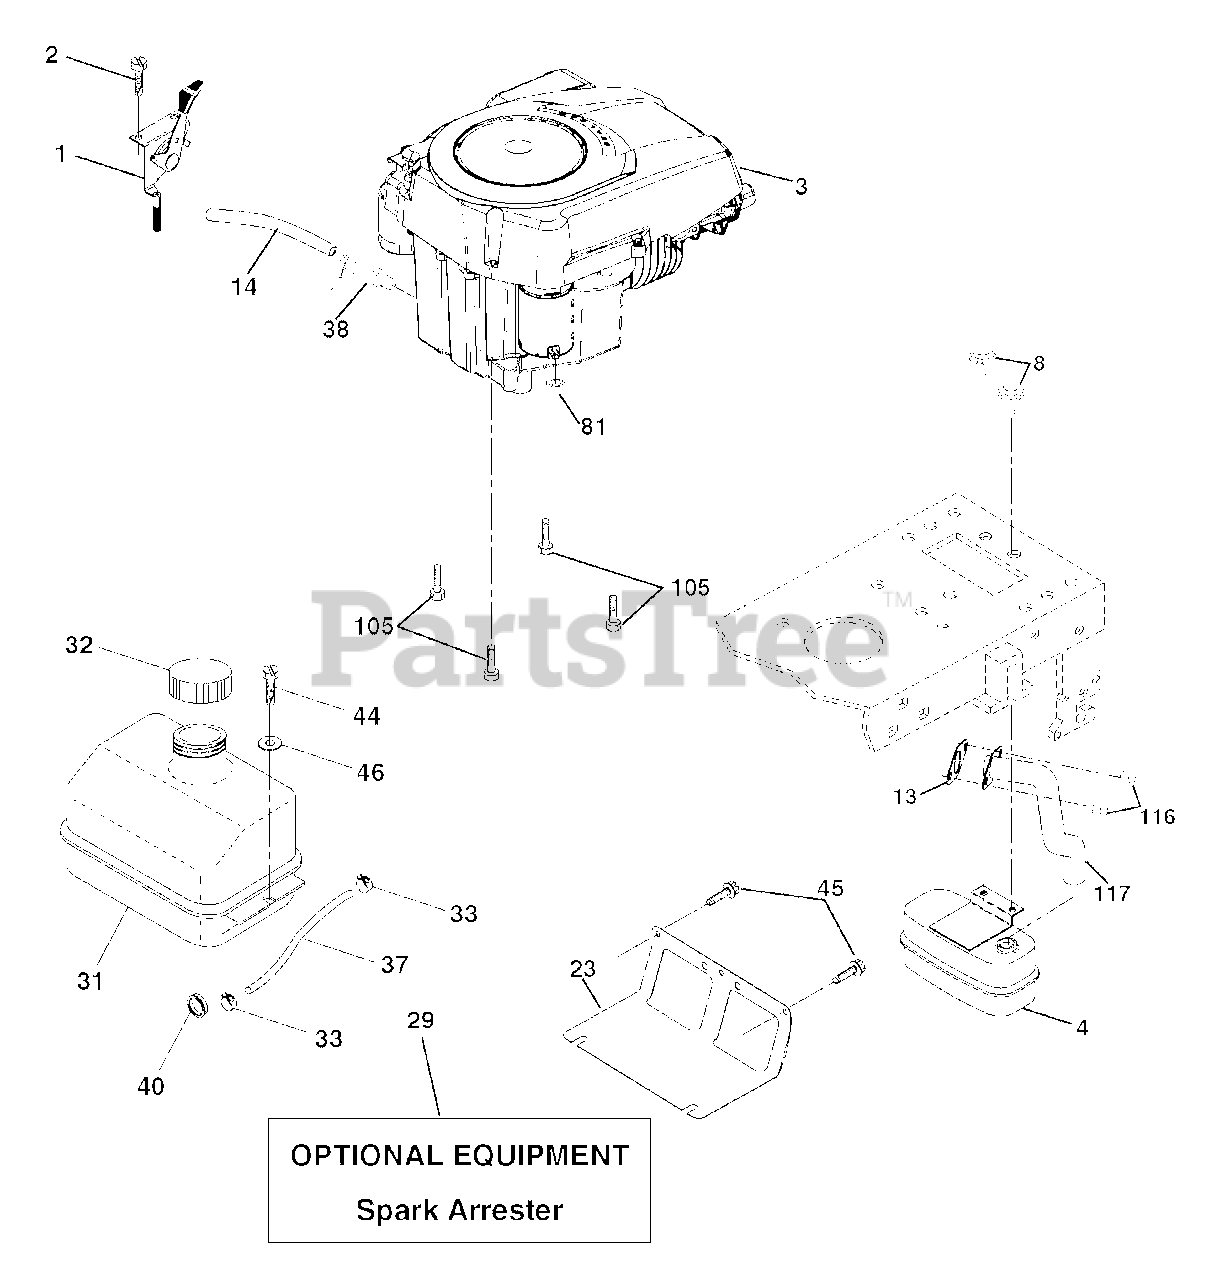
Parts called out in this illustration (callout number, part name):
1	Control, Throttle/Choke
2	Screw Hex Thd Cut 1/4-20 x 1/2
8	Bolt 5/16-18 unc x 3/4 w/Sems
13	Muffler Gasket
14	Tube Oil Drain
23	Shield, Browning/Debris Guard
29	Arrester, Spark
31	Tank, Fuel w/Cap
32	Cap, Fuel
33	Clamp, Hose Blk
37	Line, Fuel
38	Plug Drain Oil Easy
40	Bushing Snap
44	Screw 1/4-20 x 3/4
45	Screw Hex Wsh Thdrol 3/8-16 x 3/4
46	Washer 9/32 x 7/8 x 16 Ga.
81	Nut Keps Hex 1/4-20 unc
105	Screw 3/8-16 x 1
116	Nut Hex Flange Toplock M8-1.25
117	Exhaust Tube
